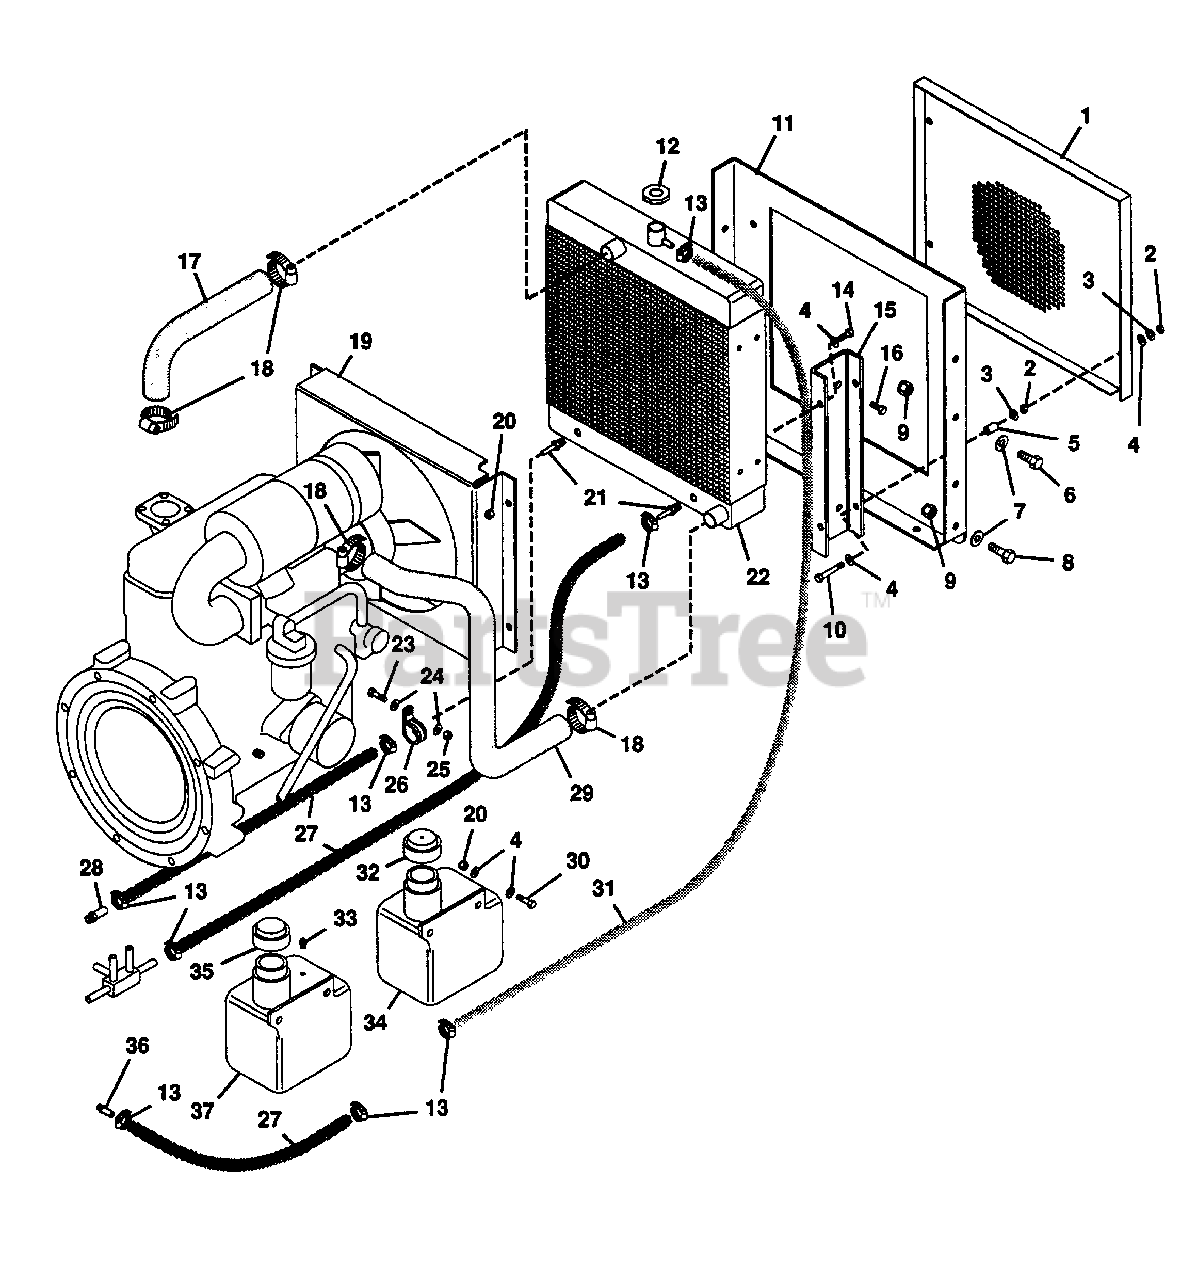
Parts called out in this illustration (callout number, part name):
1	Cover, Air
2	Nut, Hex 5/16-18
3	Washer, Lock 5/16 Reg.
4	Washer, Flat .344x.688x.065
5	Stop, Chute
6	Bolt, Hex 1/2-13x1.00
7	Washer, Flat .531x1.062x.095
8	Bolt, Hex 1/2-13x1.50
9	Nut, Lock 1/2-13
10	Bolt, Hex 5/16-18x2.00
11	Mount, Radiator
12	Cap, Radiator
13	Clamp, Hose
14	Bolt, Hex 5/16-18x.75
15	Bracket, Radiator
16	Bolt, Hex 5/16-18x.50
17	Hose, Upper Radiator
18	Clamp, Hose
19	Cover, Fan
20	Nut, Lock 5/16-18
21	Adapter, #4404-6-6
22	Radiator, Flat Plate
23	Bolt, Hex 3/8-16x1.00
24	Washer, Flat .406x.812x.065
25	Nut, Lock 3/8-16
26	Clamp, Steel .625
27	Hydraulic Hose,
28	Adapter, #4604-6-6
29	Hose, Lower Radiator
30	Bolt, Hex 5/16-18x1.00
31	Hose 5/16 ID,
32	Cap, 1-5/8 Vented(Black)
33	Plug, 1/8 Vent
34	Tank, Plastic 1.5 Qt.
35	Cap, 1-5/8 Non-Vented(White)
36	Connector, Hose
37	Tank, Plastic 1.5 Qt.
